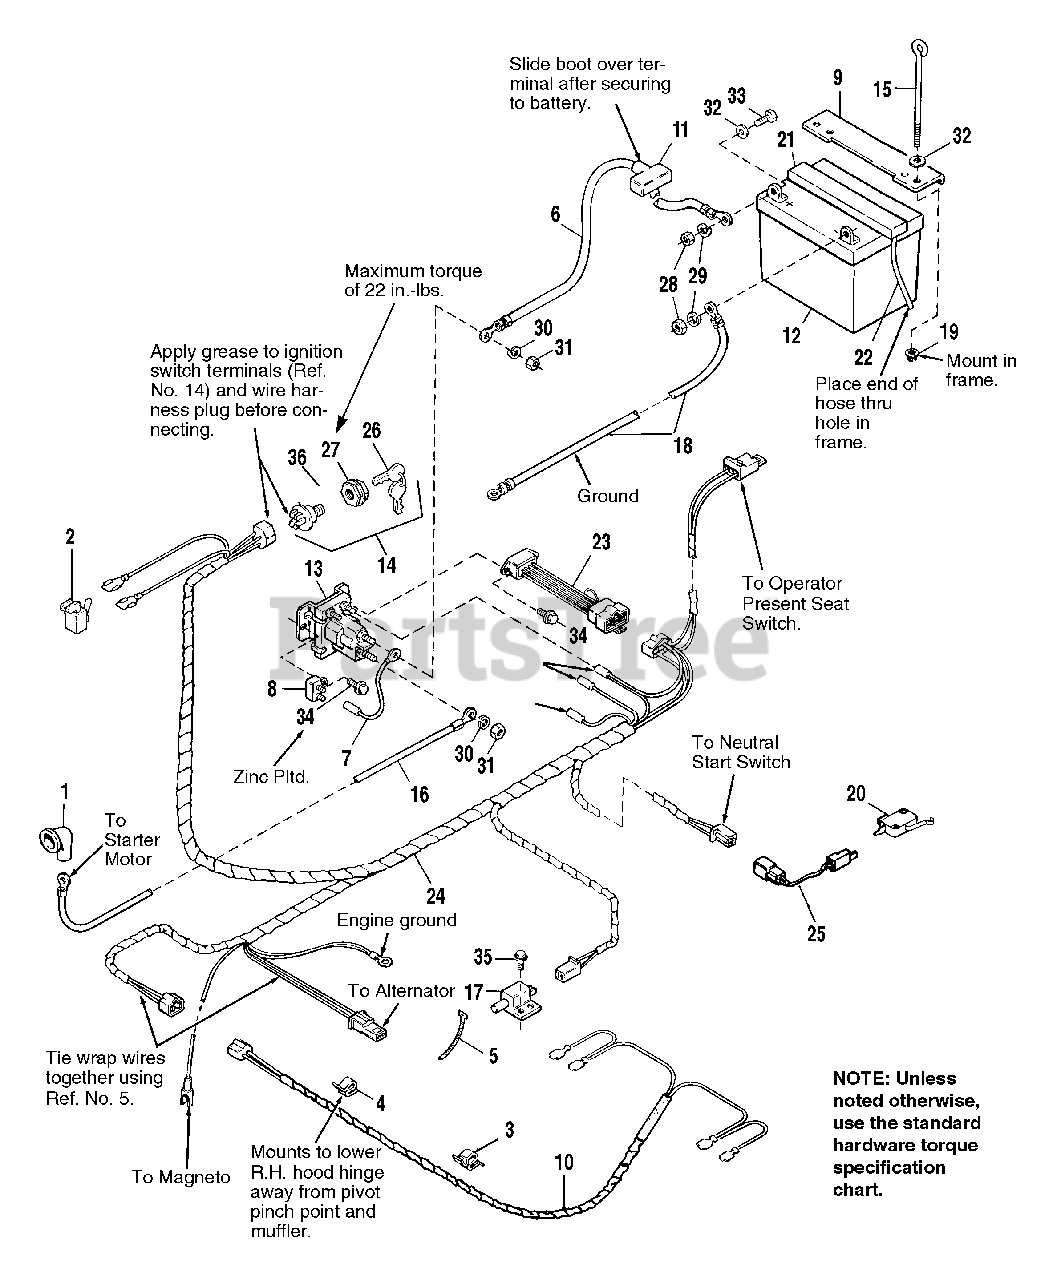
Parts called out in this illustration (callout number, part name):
1	COVER, Terminal
2	SWITCH, Headlight
5	TIE, Cable
6	CABLE (Positive)
8	CIRCUIT BREAKER
9	HOLD DOWN, Battery
10	WIRE ASSY., Headlights
11	BOOT, Insulator
13	SOLENOID
14	SWITCH, Ignition
15	ROD, Battery Hold Down
17	SWITCH, PTO
18	CABLE, Ground (Negative)
19	NUT, Retainer, 1/4-20
20	SWITCH, Transmission Interlock
21	VENT CAP, Battery
22	HOSE, Battery Drain
23	MODULE, Interlock, Seat Switch
24	HARNESS, Wiring
25	ADAPTOR, Wire
26	KEY SET (2 keys)
27	ADAPTOR NUT
28	NUT, Hex, 1/4-20
29	LOCKWASHER, 1/4
30	LOCKWASHER, 5/16
31	NUT, Hex, 5/16-24
32	WASHER, 1/4
33	CAPSCREW, Hex Hd., 1/4-20 x 3/4
34	SCREW, Taptite, 1/4-20 x 5/8, Zinc Pltd.
35	SCREW, Taptite, #10-24 x 1/2
36	LOCKWASHER, Internal Tooth, 5/8 (Thin)
